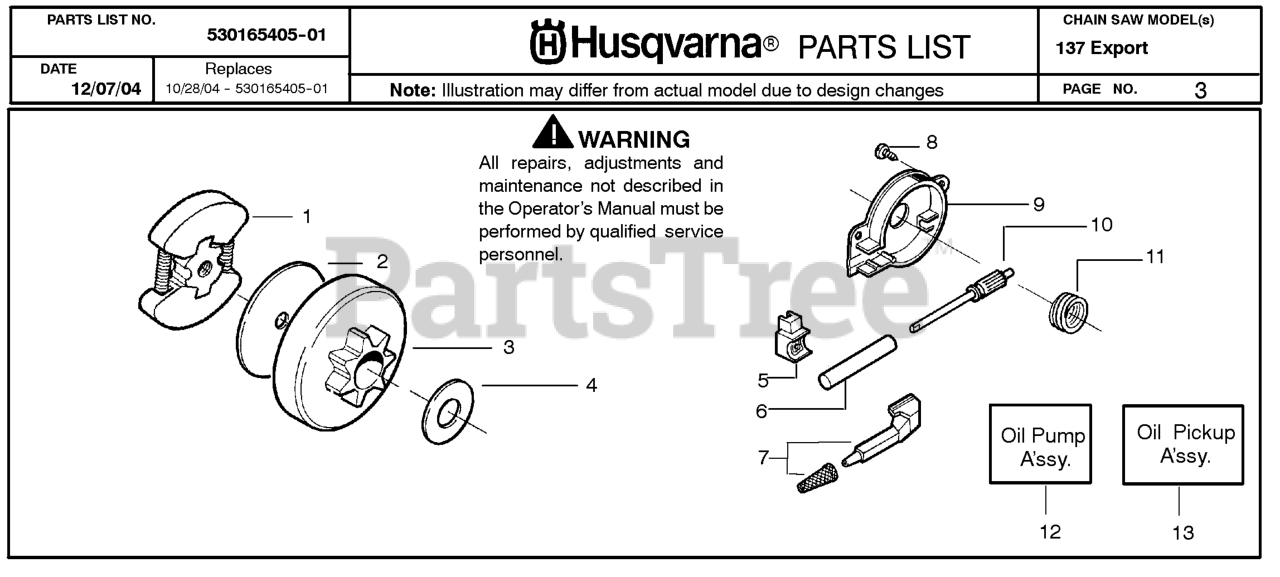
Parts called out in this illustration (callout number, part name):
1	CLUTCH ASSEMBLY
2	FRICTION DISC,CLUTCH 36/41
3	ASSY CLUTCH DRUM .325"
3	CLUTCH DRUM ASSY
4	THRUST WASHER
5	PRESSURE SEAL,OILER 36/41
6	OIL PUMP BARREL
7	OIL PICKUP
9	OIL PUMP HOUSING
10	PLUNGER & GEAR ASSEMBLY
11	OILER GEAR 36/41
12	OILER ASS'Y 36/41
13	SERVICE KIT-OIL PICKUP 36/41
